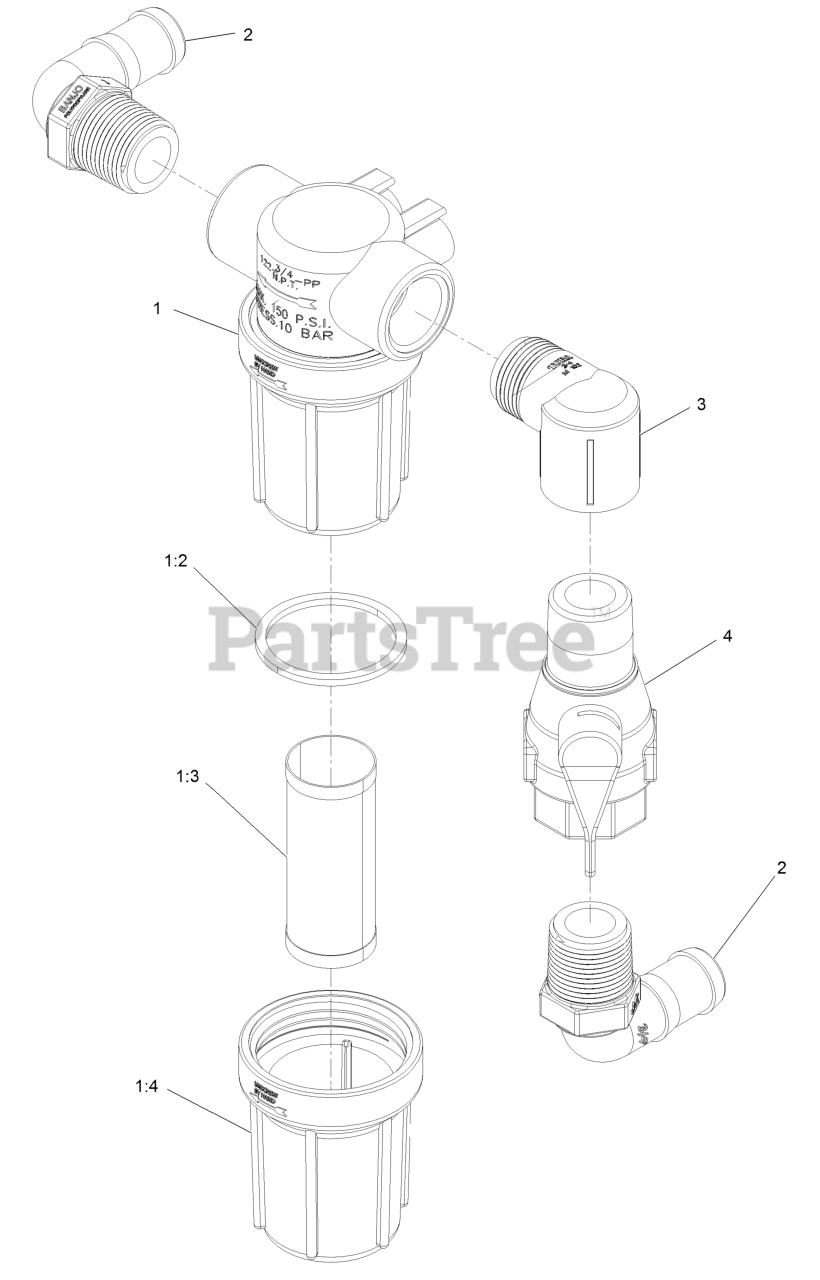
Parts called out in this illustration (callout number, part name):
1	STRAINER-LINE
1:2	GASKET-HEAD, LINE STRAINE
1:3	SCREEN-STRAINER, 30 MESH
1:4	BOWL-STRAINER
2	ELBOW-HOSEBARB
4	VALVE-BALL
